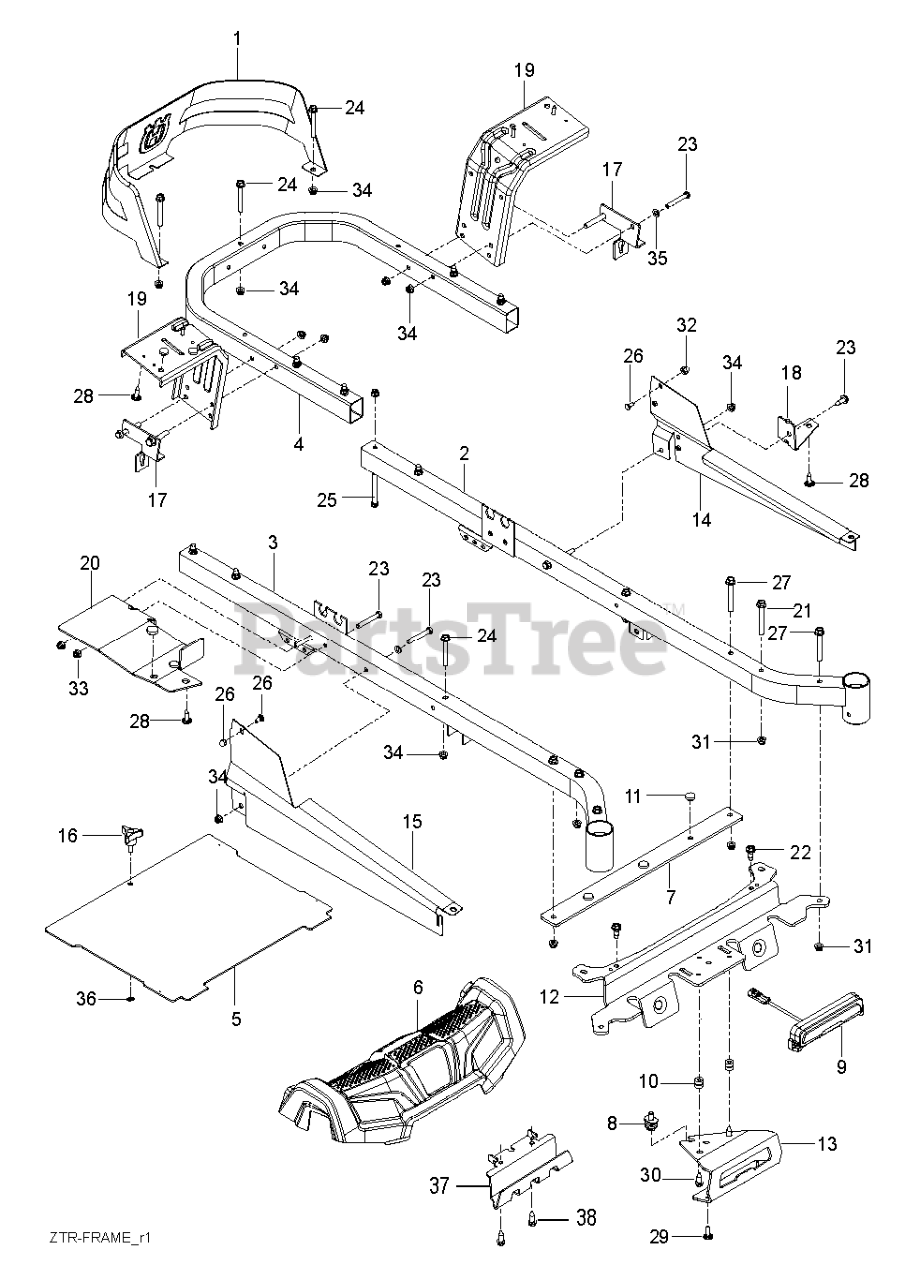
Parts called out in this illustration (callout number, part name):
1	GUARD.ENGINE.HUSQ.RZ.X498
2	FRAME.TUBE.RZ.MAIN.WELD.RH.ORG
3	FRAME.TUBE.RZ.MAIN.WELD.LH.ORG
4	TUBE.PNT.FRAME.RER.HUSQ.23".RZ
5	PLATE RZ FOOTREST HUSQVARNA OR
5	PLATE, FOOT W/DECALS RZ
6	COVER.FOOTREST.REFRESH.ASM
7	SUPPORT.RZ.FOOTREST.PLATE.X43
7	FOOTREST.PLATE.SUPPORT.X431
8	SCREW.ADJ.ISOLATOR.BOLT.ASSY
9	LIGHT.ZTR.LED.ASM
10	GROMMET.RUBBER.PUSHIN
11	GROMMET.BUMPER
12	CROSS.PNT.MEMBER.BLK
13	SKID PLATE RZ REFRESH STANDARD
13	BRACKET.SKIDPLTE.LED.RFRSHX417
14	COVER.RAIL.RH.RZ.X668
15	COVER.RAIL.LH.RZ.X668
16	SUPPORT RZ REFERSH LH CONSOLE
16	KNOB W/STUD
17	BRKT ROD.BYPASS.EZT.X431
18	SUPPORT RZ REFERSH LH CONSOLE
18	SUPPORT.PNT.LH.CONSOLE.FRONT
19	FENDER.SUPPORT.PNT.X431
20	SUPPORT.PNT.RH.CONSOLE.FRONT
20	SUPPORT RZ REFRESH RH CONSOLE
21	BOLT SHOULDER,FLANGED,3/8-16X3
22	BOLT.5/16-18.THRD.ROLL.SHOULDR
23	BOLT.FIN HEX 5/16-18UNC X2 1/4
25	BOLT.HEX.FIN.3/8-16 X 3.GR5
26	BOLT.CARRIAGE.5/16-18.7/16
27	HHFS 3/8-16 X 3 GRD 5 ZD
28	SCREW.#10 X 0.750.BOS
29	SCREW.#10 X 0.500
30	BOLT.5/16-18X1.25
31	NUT 3/8-16 HEX FLG NYLOC ZD
32	NUT ACORN,FLANGED,5/16-18
33	NUT LOCK HEX FLANGE 5/16-18
34	5/16-18 NYLOC FLANGE NUT
35	WASHER
36	WASHER 5/16"
37	SKID.PLATE.PNT.RZ.REF.SIVER
38	BOLT.5/16HEX.WHS.HD
